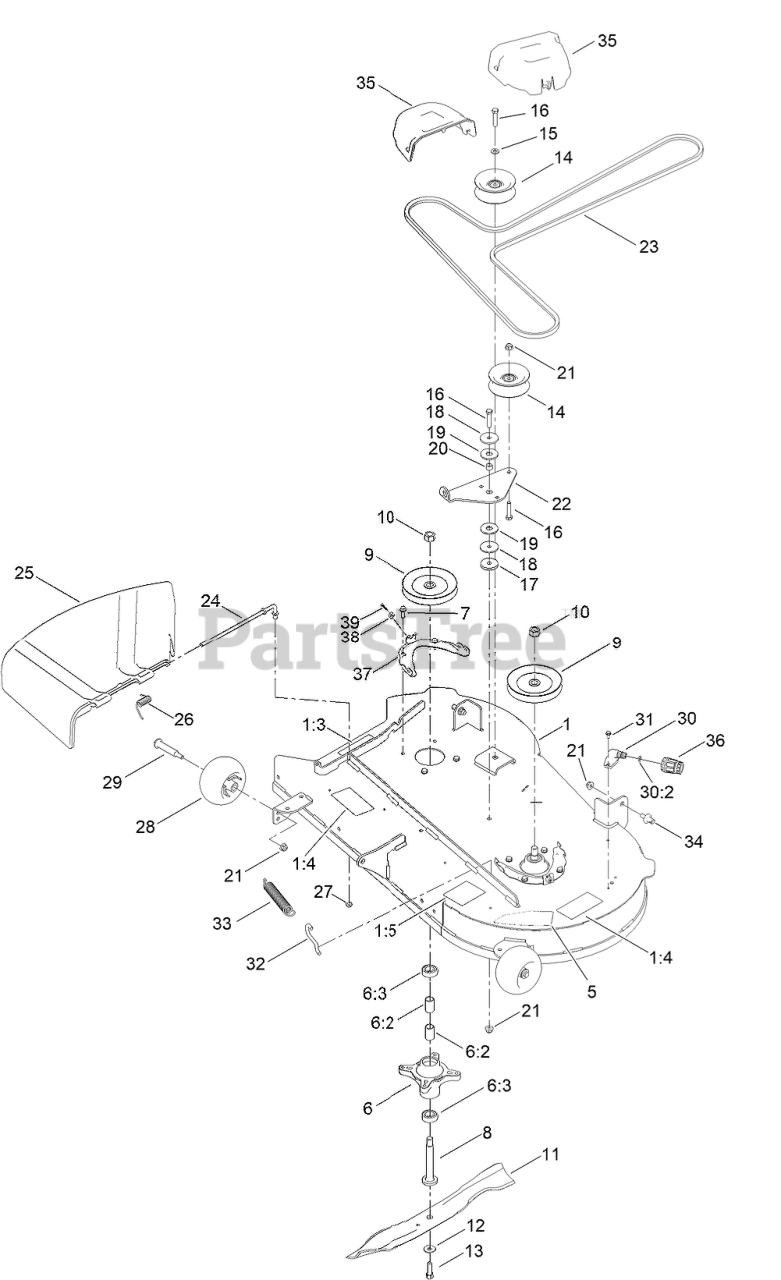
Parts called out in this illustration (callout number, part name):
1	42IN DECK AND DECAL ASM
1:3	DECAL-DANGER
1:4	DECAL-DANGER, DECK
1:5	DECAL-ROUTING, BELT
5	DECAL-DECK
6	SPINDLE ASM
6:2	SPACER
6:3	BEARING-BALL
7	SCREW-TAPTITE
8	SHAFT-SPINDLE
9	Pulley
10	NUT-HEX
11	BLADE-21.6 IN
12	WASHER-BELLEVILLE
13	SCREW-HH
14	PULLEY-IDLER, FLAT
15	WASHER-FLAT
16	SCREW-HH
17	WASHER-PLAIN
18	WASHER-REBOUND
19	WASHER-FRICTION, COMPOSITE
20	SPACER
21	NUT-HF, NI
22	ARM-IDLER
23	V-BELT
24	ROD-PIVOT
25	DEFLECTOR-DISCHARGE
26	SPRING-TORSION
28	ROLLER-SCALP, ANTI
29	BOLT-SHOULDER
30	FITTING-WASHOUT
30:2	O-RING
31	SCREW-HWH
32	HOOK-RETURN SPRING
33	SPRING-EXTENSION
34	PIN-DECK
35	COVER-BELT
36	CONNECTOR-HOSE
37	BRACKET-COVER, BELT
38	SPACER-NOTCHED
39	SCREW-PPH
